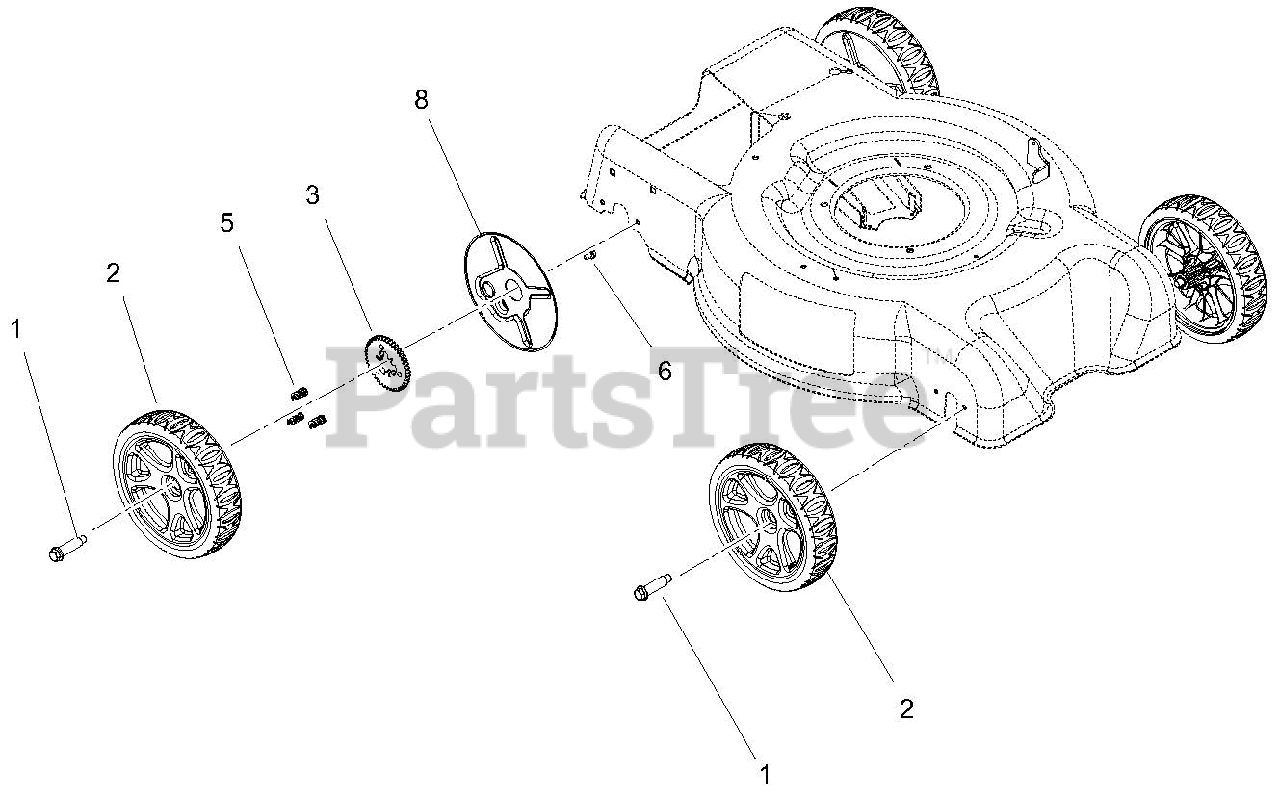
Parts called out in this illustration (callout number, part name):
1	BOLT, WHEEL SHOULDER
2	WHEEL-8.5" WBLM ASSY
3	GEAR, WHEEL
5	SCR-TAP 12-14X.75PLSTITE @BLZC
6	@SCR-TAP .25-20X.37 HWH YWZ TR
8	COVER, WHEEL-ARIENS LM SPECIAL
